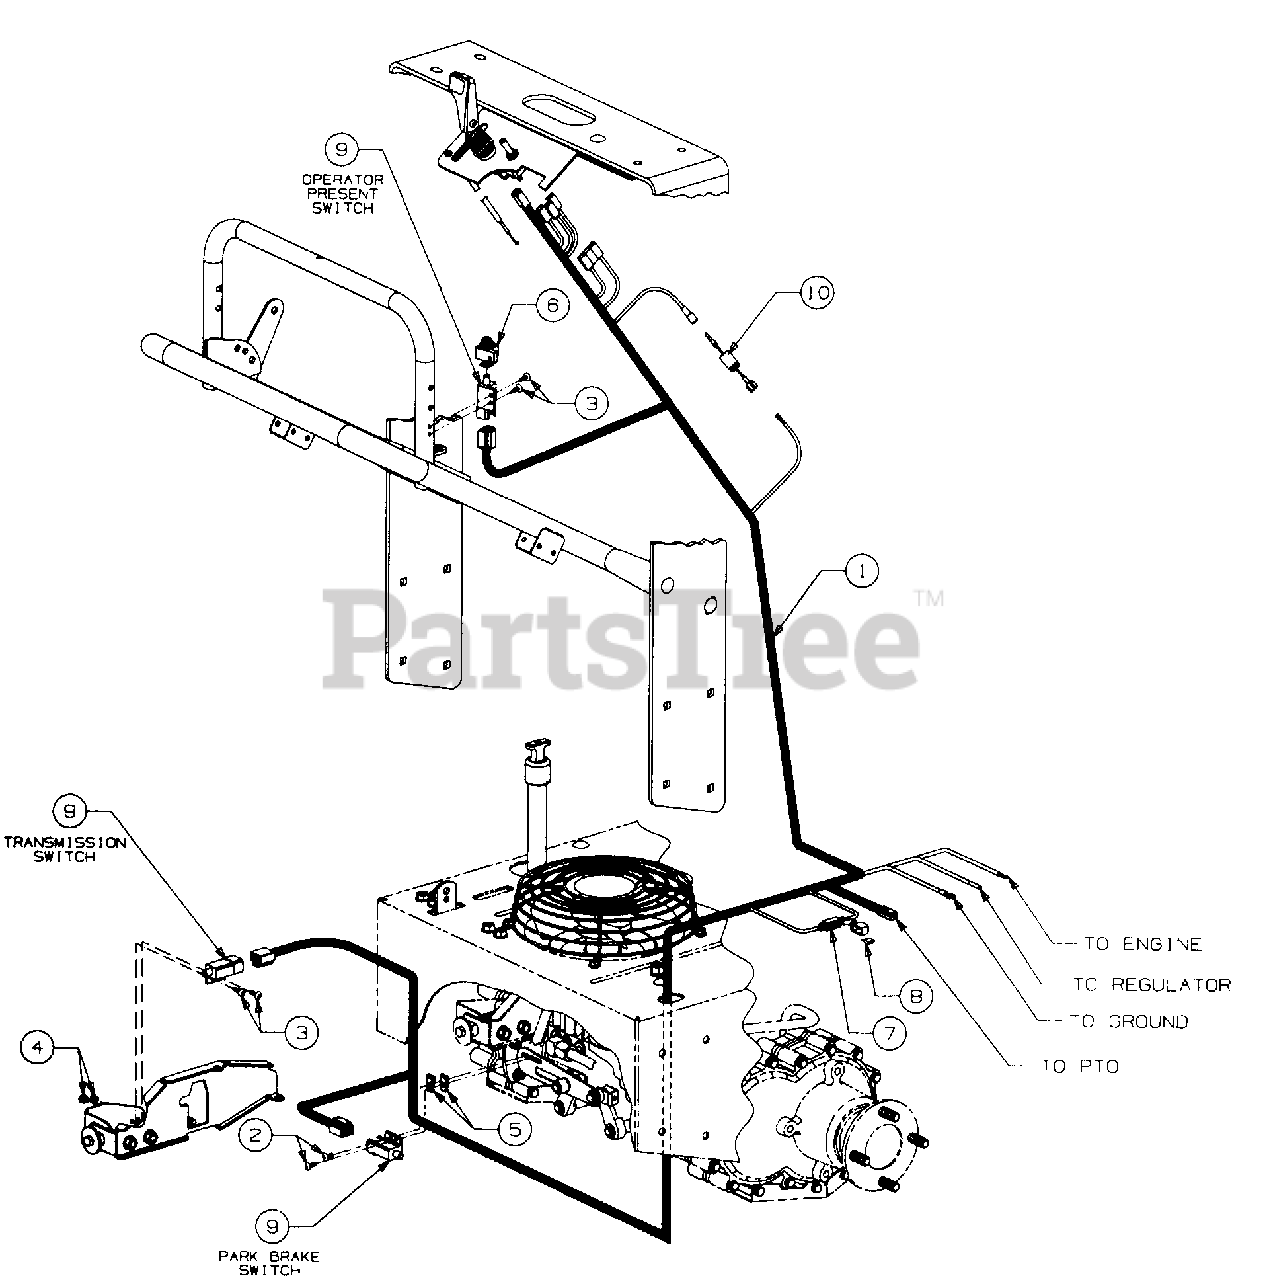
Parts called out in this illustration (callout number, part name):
2	Screw, Truss Mach, #10-24 X .50 Lg
3	Screw, Pan Hd Cutting, #10-24 X .75 Lg
4	Nut, Hex Lock, #10-24
5	Nut, Speed
6	Cover, Protective
7	Holder, Inline Fuse
8	Fuse, 20 Amp Mini
9	Switch, Double Poled Plunger
10	Capacitor, Clutch
